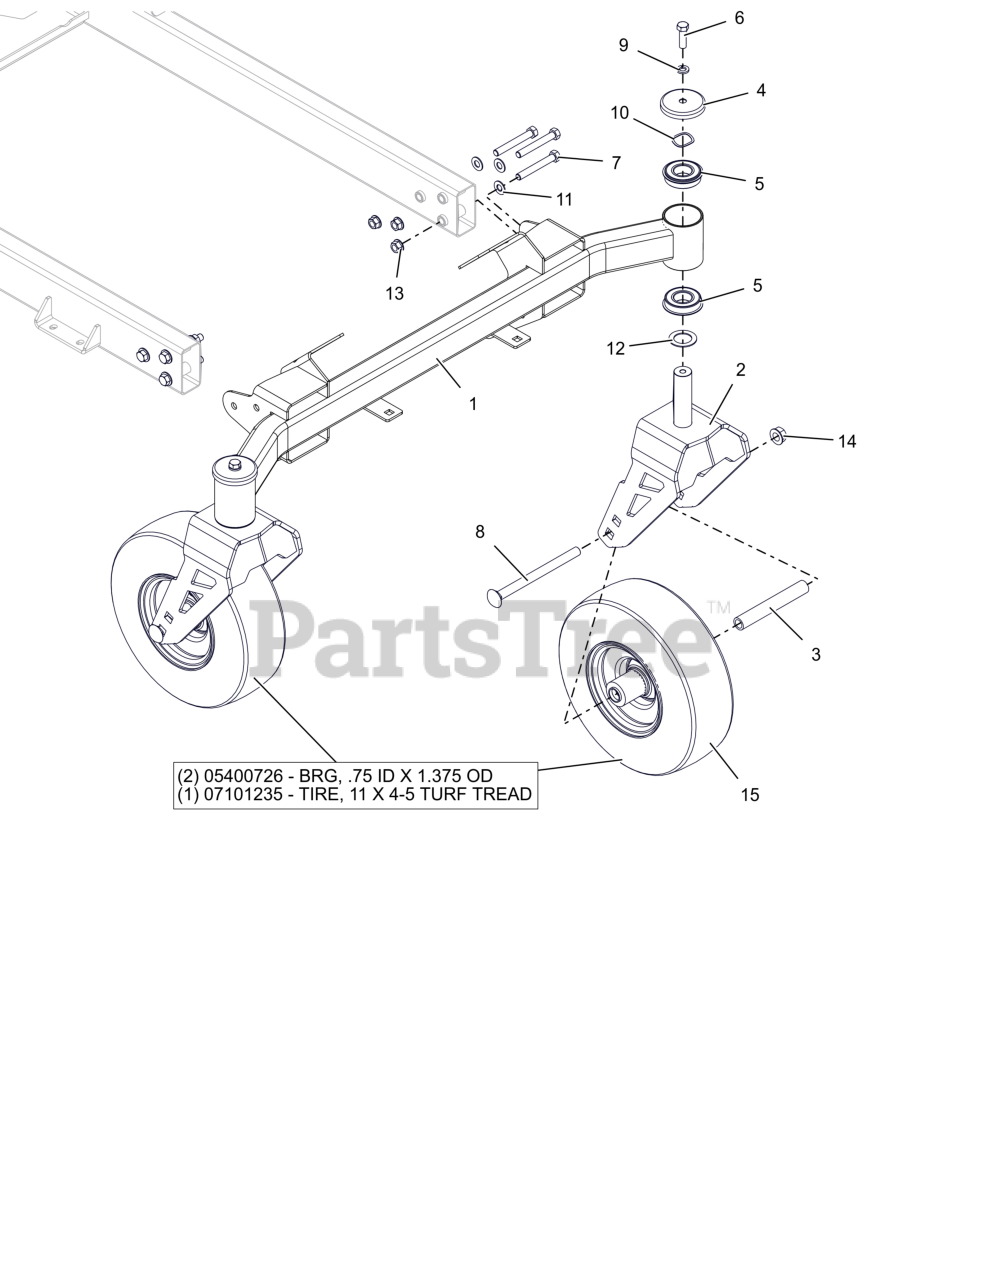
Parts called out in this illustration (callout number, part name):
1	WMT-FRONT AXLE-X/XL
2	WLDMT, CASTER FORK-XD (ORANGE)
3	SPACER, ROLLED WHEEL
4	SHIELD, AXLE BEARING
5	BEARING, BALL -2.000 OD X 1.000 ID X .5625 W/RING
6	BLT, HEX .38-16X1.25 G5 ZCC
7	BLT, HEX .38-16X2.75 G8 ZCC
8	BLT, RHSN .50-13X6.50 G5 ZCC
9	WSHR,LK-REG .375X.094 ZCC
10	WSHR-WAVE 1.0X1.25X.028 .145FH
11	WSHR,FLT-HRD.406X.812X.055 MZC
12	WSHR-HRD-THRS 1.007X1.542X.062
13	NUT-LK-TOP-FLG .375-16 GG ZCC
14	NUT-LK-TOP-FLG .500-13 GF ZCC
15	ASM, WHL/TIRE 11X4.00-5
15	BRG, .75 ID X 1.375 OD
15	LAWN TIRE FRONT, 11/4-5 TURF TREAD
15	VALVE STEM ASS'Y
15	TIRE TUBE, 11/4.0-5 4 PLY TR87 90 BENT VALVE
